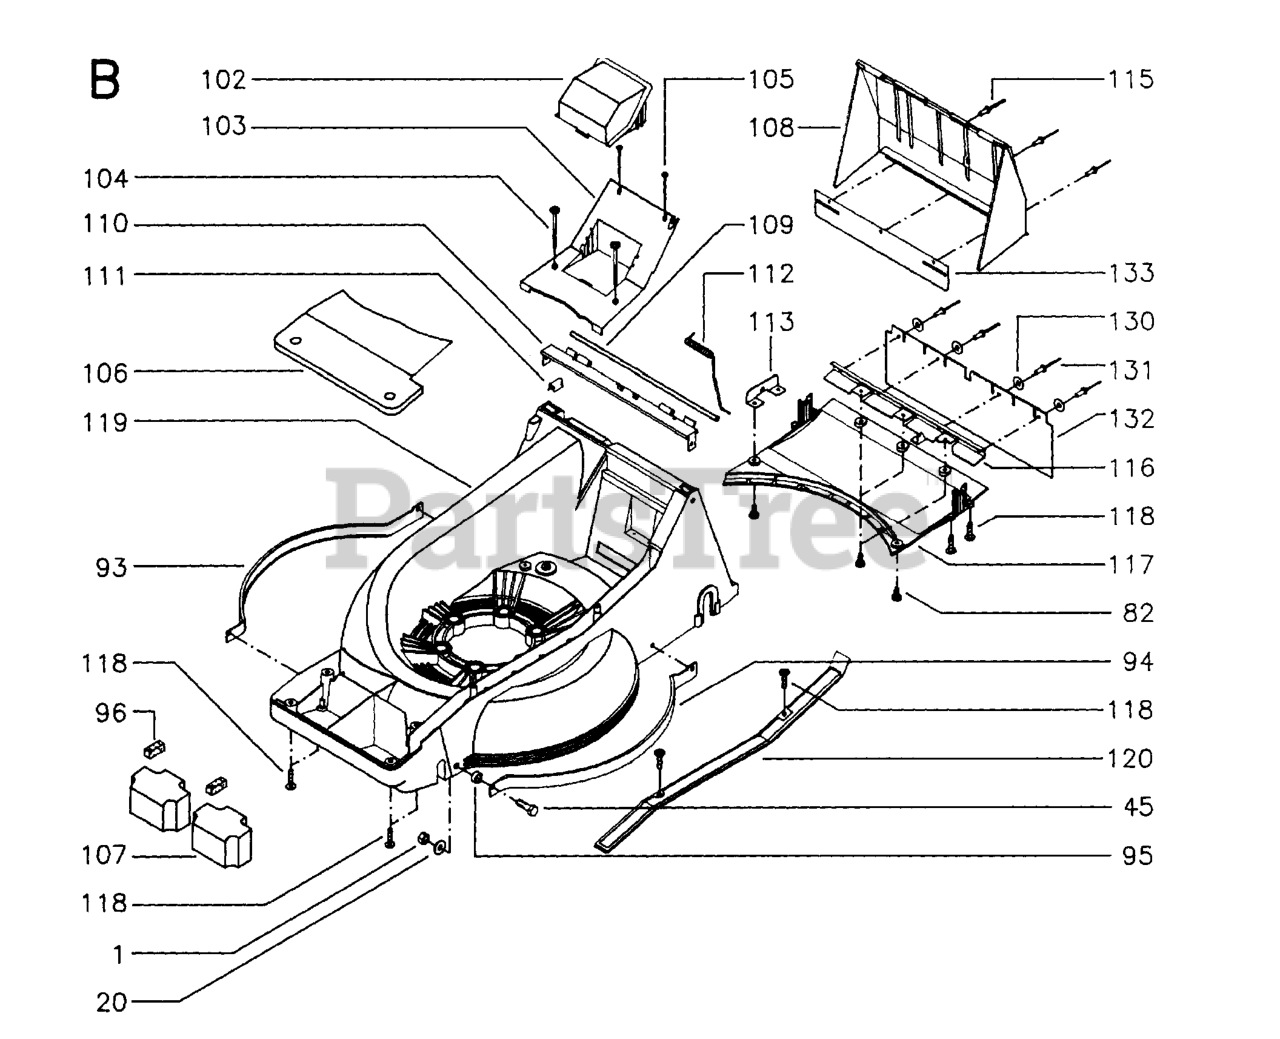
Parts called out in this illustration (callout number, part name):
1	LOCKNUT M8
45	SCREW M6S 8X25
93	DECK PROTECTOR RH
94	DECK PROTECTOR LH
106	DECK FRONT COVER
107	COUNTERWEIGHT
110	BRACKET
113	BRACKET
120	COVER
